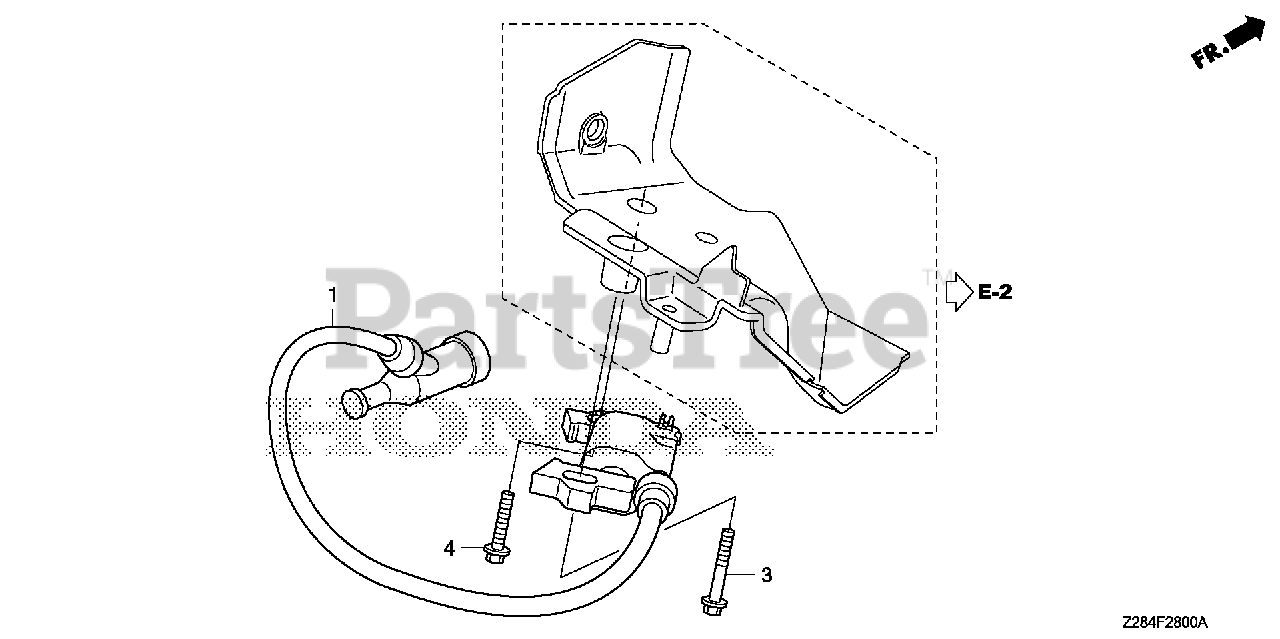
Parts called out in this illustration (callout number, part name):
1	COIL ASSY., IGNITION
3	BOLT, FLANGE (6X35) (CT200)
4	BOLT, FLANGE (6X20)
